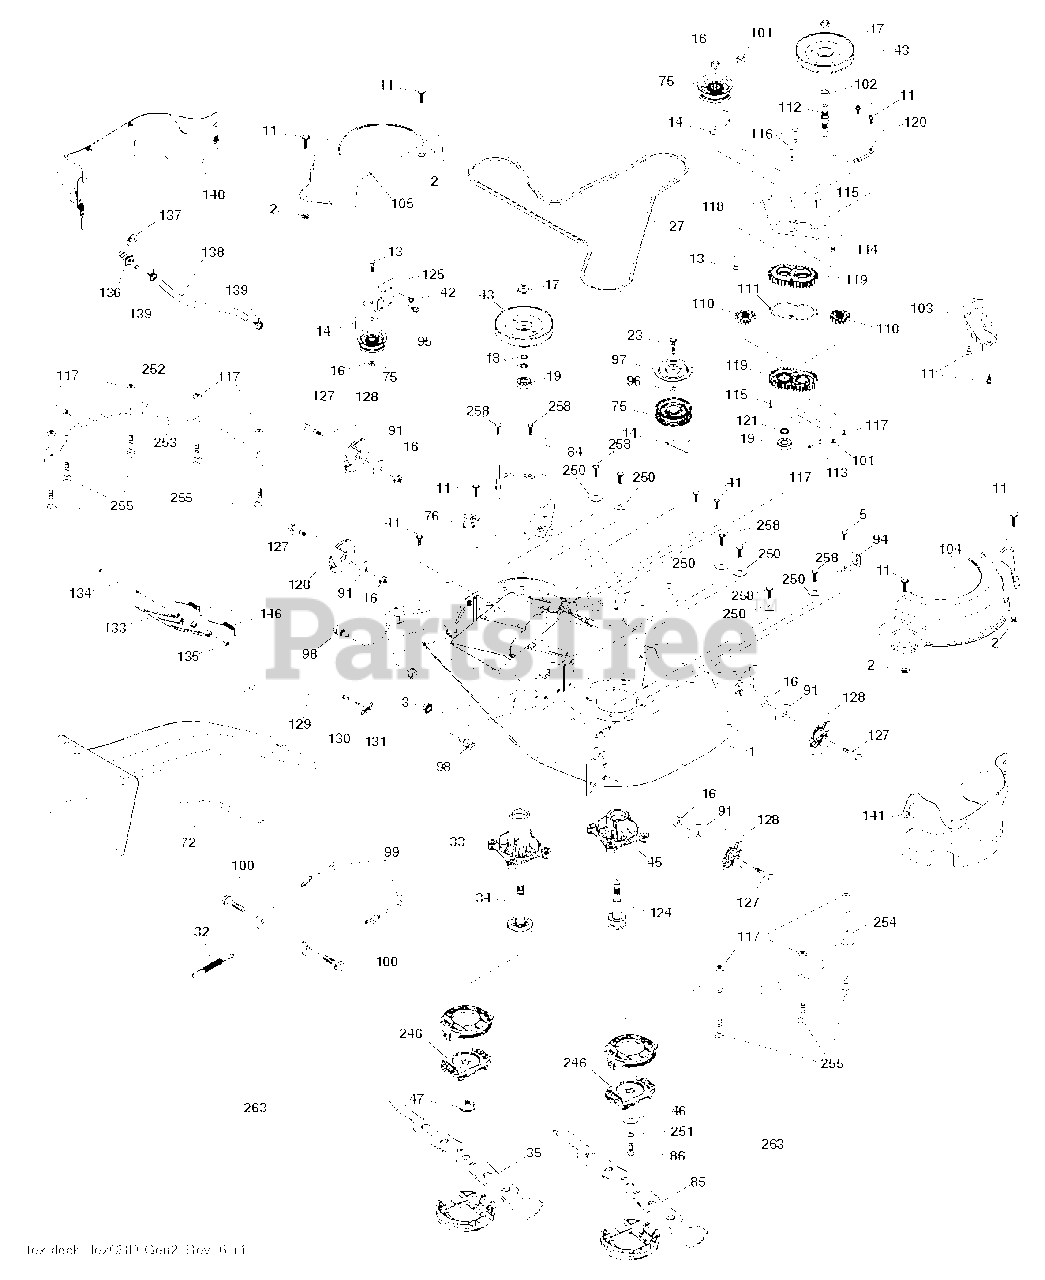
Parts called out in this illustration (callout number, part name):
1	DECK.SVC.WLDT.97EL.TCRD.EZ.498
2	PALNUT 1/4
3	NUT LOCK HEX FLANGE 5/16-18
5	BOLT.5/16HEX.WHS.HD
11	SCREW.1/4-20X5/8
13	BOLT.3/8-16X1.50
14	KEEPER, BELT IDLER
16	NUT LOCK FLG 3/8-16 UNC
17	NUT.FLANGE.LOCK.TOP
18	WASHER.SPACER.MANDREL
23	SCREW LT
27	BELT 97CM ELECTRIC
32	SPRING 107CM & 97CM ELECTRIC D
33	HOUSING.MANDREL.REV.TALL.N/GRS
34	SHAFT ASM.REV.TALL.N/GREASEBL
35	BLADE.REVOLUTION.97CM.LHS
41	BOLT.HEX.WASHR.HED.313-18X1.19
42	SCREW
43	PULLEY.MANDREL.5.0.PD.38"
45	RP HOUSING.MANDREL.REV.REVS.
46	3/8 FLAT WASHER
47	SCREW.SEMS.7/16-20X1.HEX.HEAD
72	RB CHUTE 107/97 TEX GENII
75	FLAT IDLER PULLEY
76	1/2" BARB.DECK.WASHOUT.PORT
84	BELT KEEPER.MANDREL.38"COATED
85	BLADE.REVOLUTION.97CM.RHS
86	BOLT.3/8-24X1.25GR8. LHTHRD
91	WASHER
94	BRKT.CLUTCH.CABLE
95	SCREW, 3/8-16X3/4
96	SPACER
97	PROTECTOR
98	STUD.FASTNER.W/ANTI-ROTATE
99	ARM.SUSPENSION.MOWER.R
100	BOLT.SHOULDER
101	NUT.CROWNLOCK.9/16 -18.UNC
102	SPACER BEARING
103	GUARD GUARD FRONT VENT
104	97.CRD.RH.MANDREL.COVER
105	MANDREL MANDREL COVER LH
110	GEAR GEAR OUTPUT
111	GASKET GASKET GEARCASE
112	SHAFT SHAFT. CRD GEARCASE ADAP
113	PLUG PLUG OIL
114	VALVE VALVE RELIEF
115	SCREW
116	BOLT.CARIGE.SS.1/4-20X1.75GR5
117	NUT T
118	ARM ARM CLUTCHING
119	GEARCASE GEARCASE SUBASM
120	BRACKET KEEPER BELT RH
121	WASHER WASHER
124	SUB.ASM.REVERSE.THREAD.REV
125	BRACKET
127	BOLT.SHOULDER.3/8-16X3-5/8.
128	WHEEL. GUAGE RALLY
129	ROD ROD. SWAY CRD GEN II
130	WASHER
131	PIN.COTTER.5/16.BOW TI
133	DOOR
134	PIN PIN.HINGE
135	E-RING.5/16"
136	PLUG WASHOUT PORT HOOKUP
138	HOSE.3/8ID.BULK.12"
139	HOSE.3/8.CLAMP (2 2)
140	GUARD
141	GUARD SUBASM.TEX CRD 97CM RH F
146	SPRING SPRING: EZ MULCH DOOR
246	HOLDER.BLADE.REVOLUTION
251	LOCKWASHER
252	PLATE.REINFORCEMENT.X431
253	PLATE.REINFORCEMENT.LHS.X431
254	PLATE.REINFORCEMENT.LHS.X431
255	RHSNB, 1/4-20 X 1, GR5
258	BOLT.HEX.WASHR.HED.313-18X1.19
263	CAP.REVOLUTION ASM
